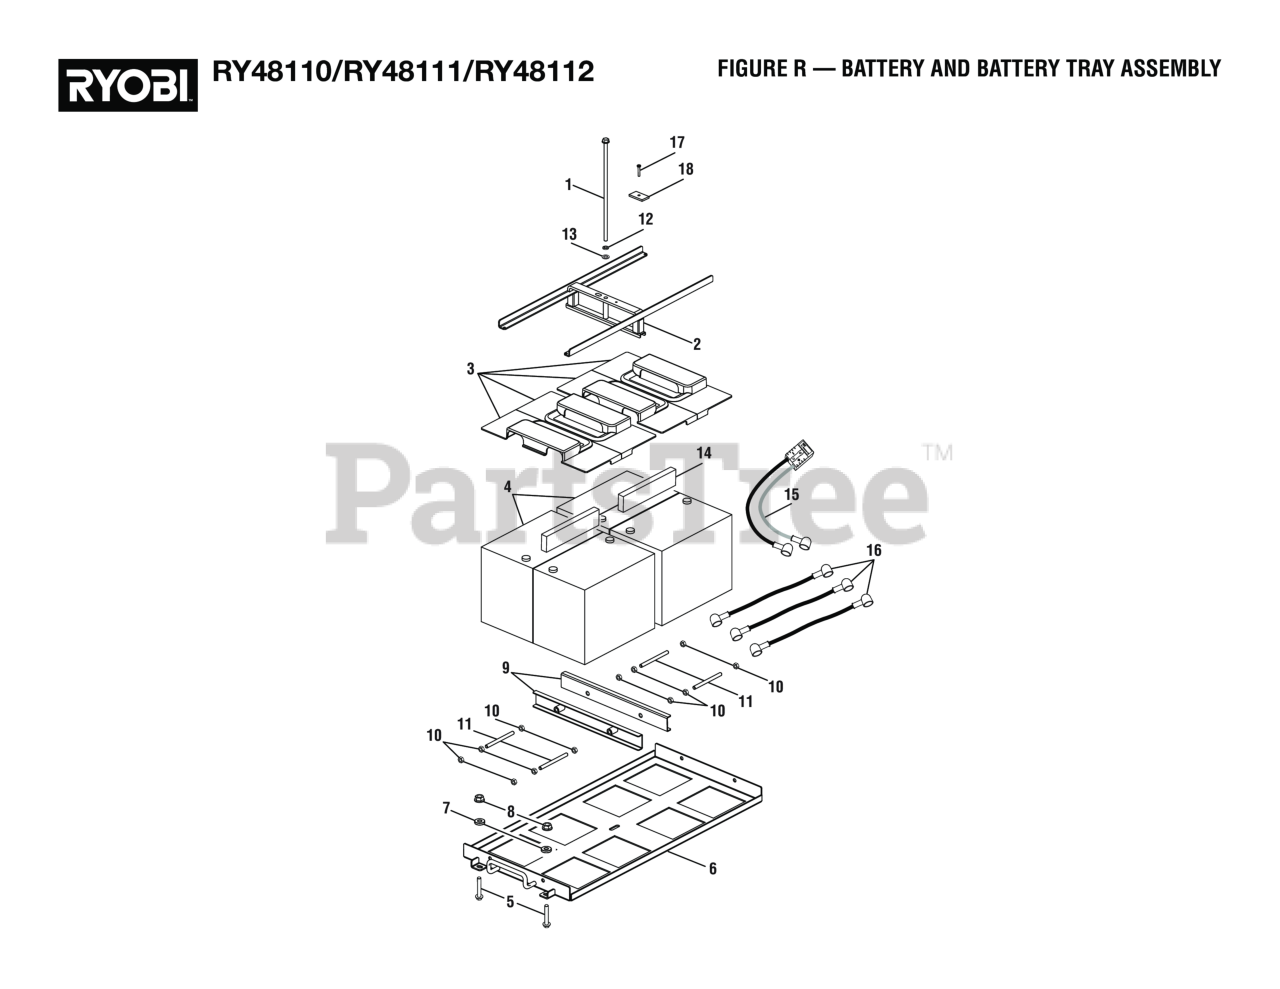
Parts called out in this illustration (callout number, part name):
1	Bolt (M8)
2	Battery Tie Down
3	Battery Cover
4	Battery (LPC12-75, RY48110, RY48112)
5	Bolt (M8 x 55 mm, Flange Hex Hd.)
6	Battery Tray
7	Metal Bushing
8	Flange Nut (M8) (For Drive Motor Controller V)
9	Battery Holder Bracket
10	Hex Nut (M8)
11	Threaded Rod (M8 x 100 mm)
12	Lock Washer (OD9.8 x ID8.5 x 5t)
13	Washer (OD12.5 x ID8.4 x 4t)
14	Battery Spacer (LPC12-75)
15	Two Wire Battery Cable (4 AWG Black & 4 AWG Red, 250 mm)
16	Battery Cable w/Covers (Red and Black, 120 mm)
17	Screw (M5 x 30 mm, Cross Recess Pan Hd.)
18	Main Connector Washer
